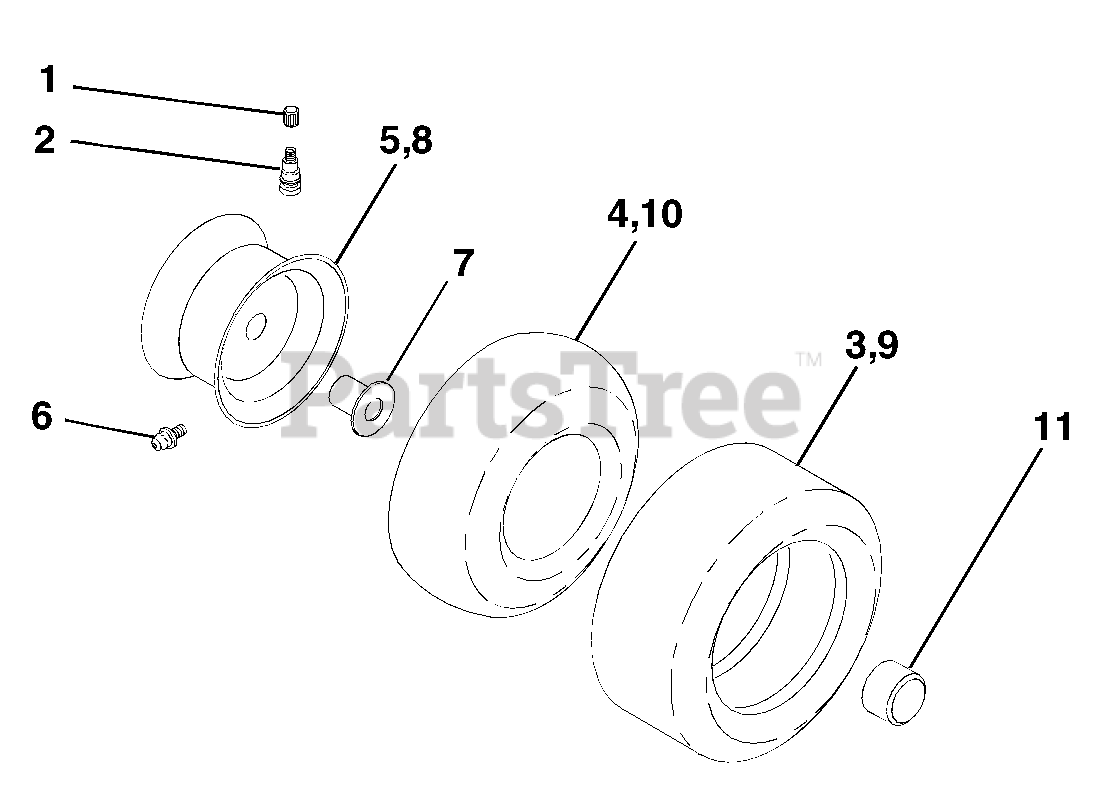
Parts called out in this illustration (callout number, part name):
1	Cap Valve Tire
2	Stem Valve
3	Tire F Ts 15 X 6 0 - 6 Service
4	Tube Front (Service Item Only)
5	Rim Asm 6"front Service
6	Fitting Grease (Front Wheel Only)
7	Bearing Flange (Front Wheel Only)
8	Rim Asm 8"rear Service
9	Tire R Ts 20X10.00-8 C Service
10	Tube Rear (Service Item Only)
11	Cap Axle Blk 1 50 X 1 00
